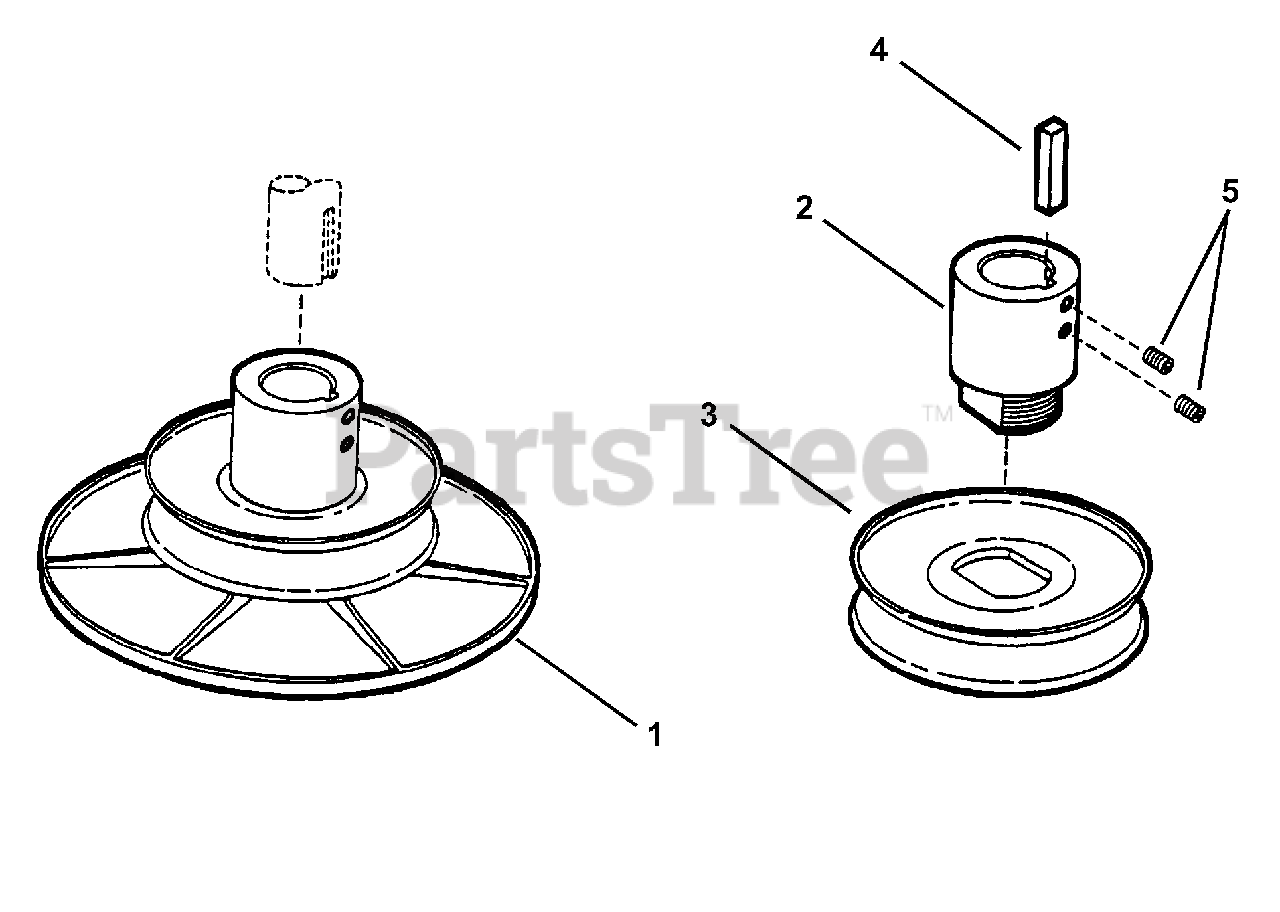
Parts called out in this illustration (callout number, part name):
1	ASSEMBLY, Drive Disc - Steel (5.75" OD Pulley)
2	HUB
3	PULLEY, Drive (5.75" O.D.)
4	KEY (1/4"sq. X 2")
5	SCREW, 3/8-16 x 3/8" Set
